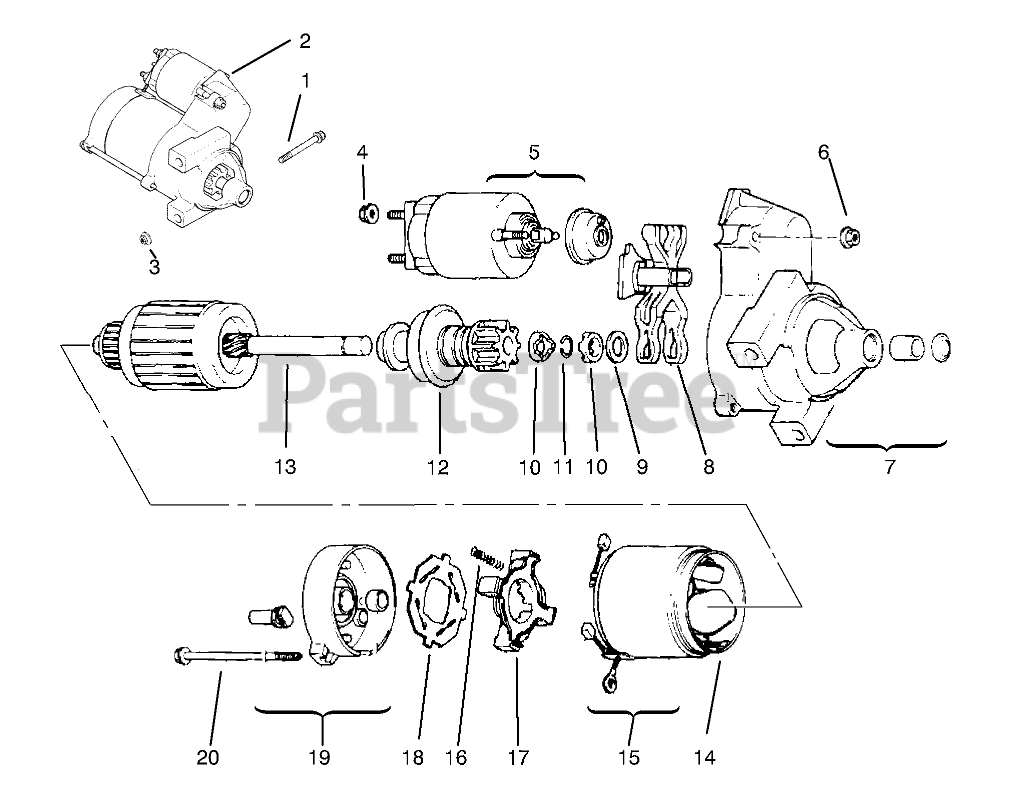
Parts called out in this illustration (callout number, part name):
2	Starter INC 4-20
4	Nut
5	Solenoid
6	Nut
7	Cap Drive End
8	Lever Starter Drive
9	Washer-Thrust
10	Nut
11	Ring-Retainer
12	Drive Pinion
13	Armature
14	Frame
15	Brush Kit
16	Spring Brush
17	Holder-Brush
18	Insulator
19	Cap-Commutator End
20	Bolt
